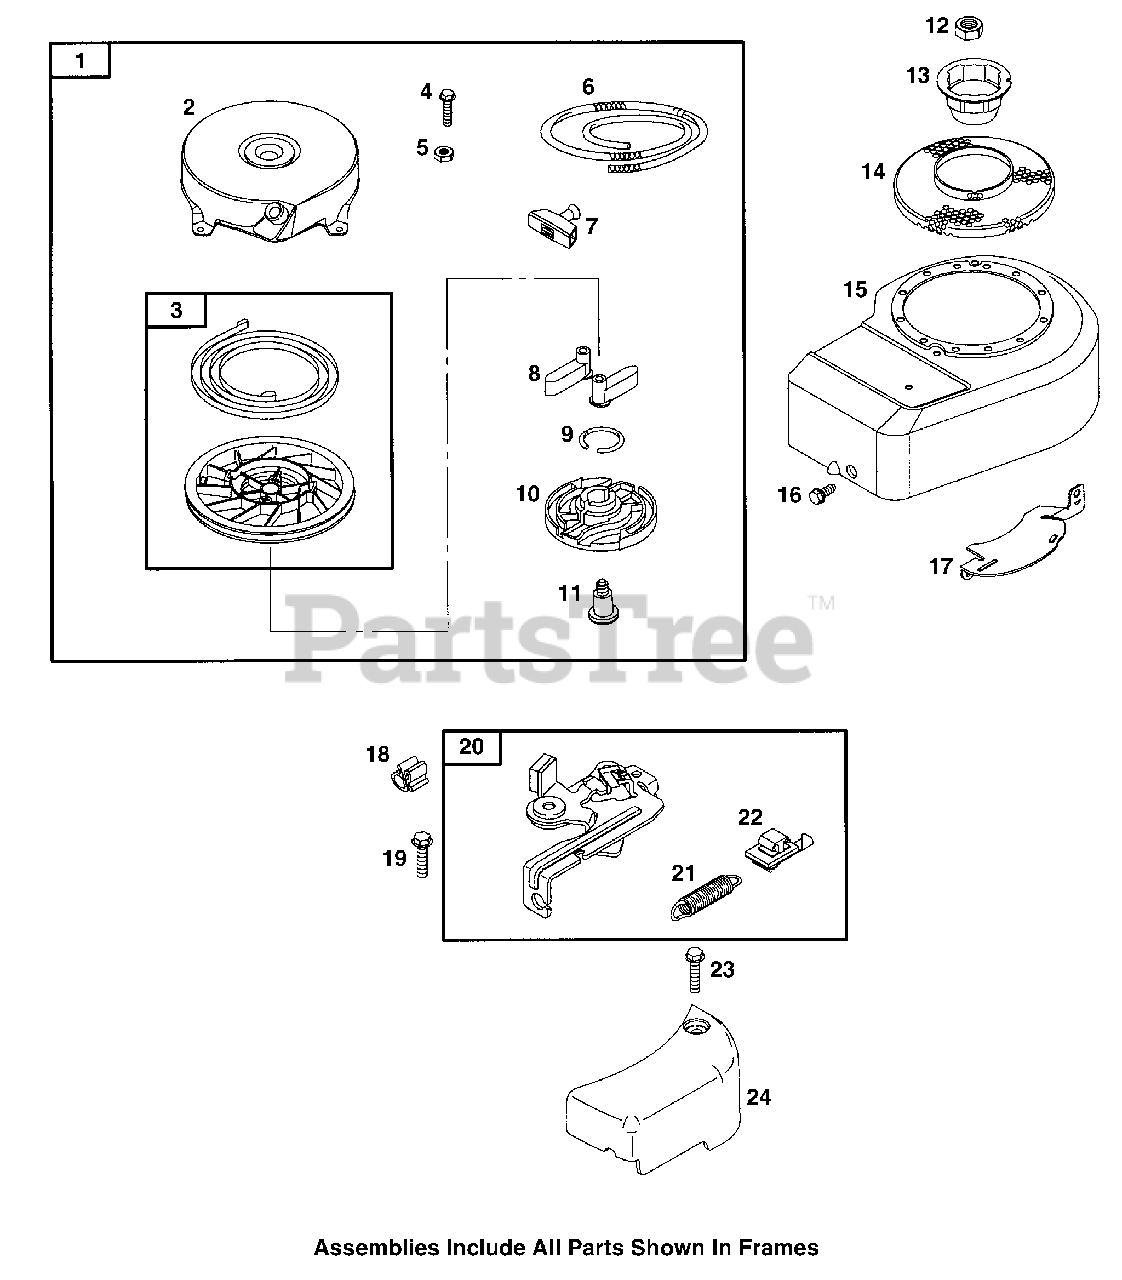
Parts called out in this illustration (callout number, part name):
1	Rewind Starter
2	Rewind Starter Housing
3	Pulley Spring Assembly
4	Hex Screw
5	Hex Nut
6	Starter Rope
7	Starter Rope Grip
8	Rachet Pawl
9	Friction Spring
10	Pawl Friction Plate
11	Shoulder Screw
12	Flywheel Nut
13	Flywheel Cup
14	Rotating Screen
15	Blower Housing
16	Hex Screw
17	Flywheel Guard
19	Hex Screw
20	Brake Bracket
21	Brake Spring
22	Stop Switch
24	Linkage Cover
